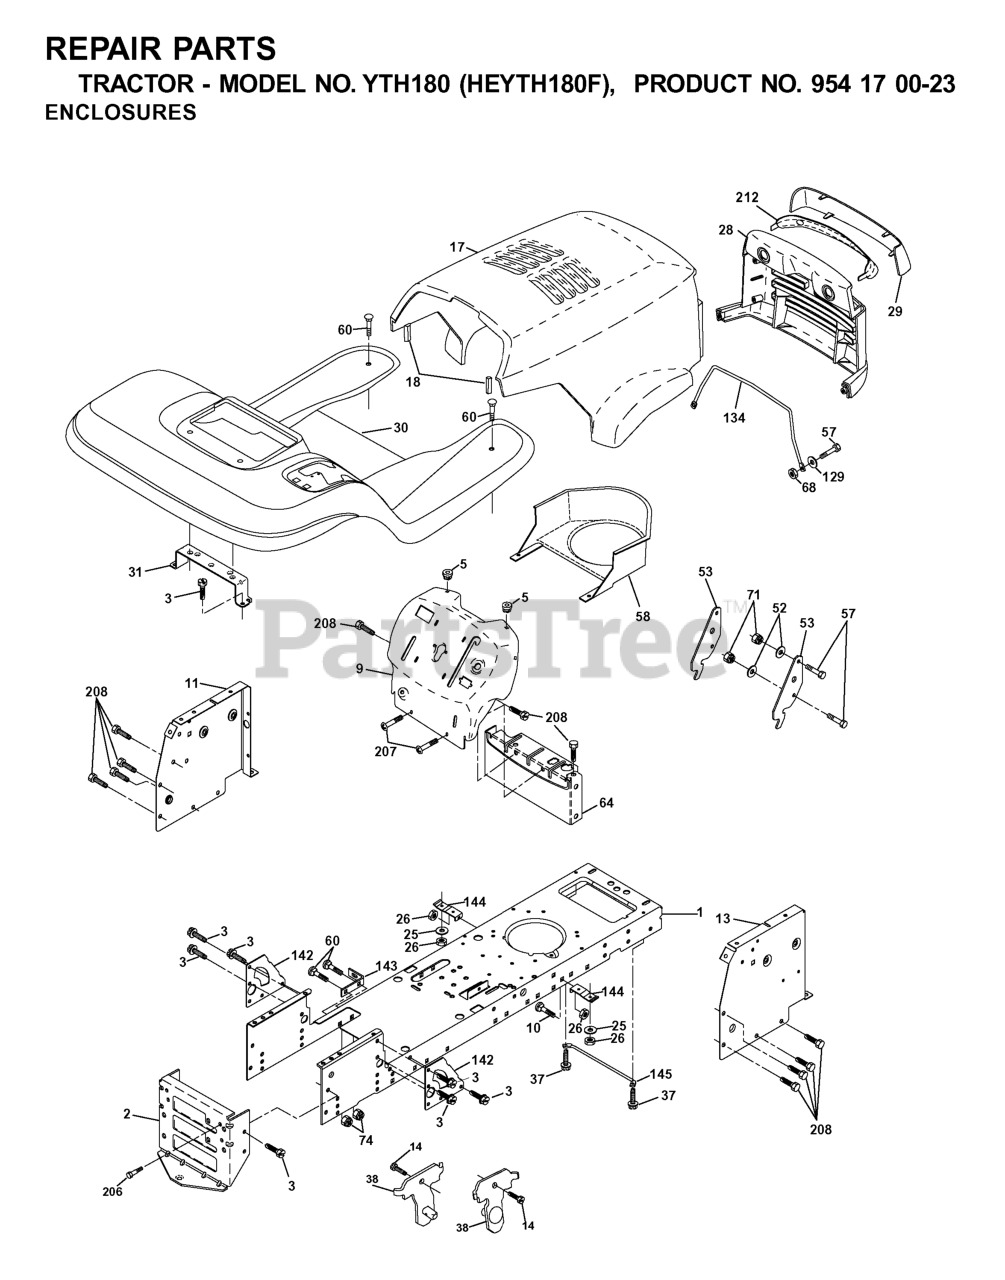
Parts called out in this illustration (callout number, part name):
1	CHASSIS STAMPING
2	DRAWBAR, 12GA
3	SCREW 3/8-16X3/4
5	BUMPER.RUBBER.HOOD
9	DASH(SUBS)
10	BOLT D
11	PANEL DASH LH
13	PANEL ASM, DASH RH
17	HOOD
18	BUMPER HOOD T
20	PLATE MTG
23	BUSHING.SNAP.NYL.BLK.
25	WASHER
26	NUT
28	GRILL
29	LENS
30	FENDER FOOTREST
31	BRACKET.SUPPORT.FENDER
37	Screw 5/16-18 x 1/2 Hex, Self Tapping 5/16-18 x 1/2
38	BRACKET.ASM.PIVOT.MOWER.REAR
53	BRACKET PNT PICK OFF LT/PL
57	BOLT
58	DUCT, INTAKE AIR
60	Bolt - Rd. Hd. Sq. Neckiage 3/8 16 x 3/4
64	DASH LOWER
68	NUT
71	NUT.CROWNLOCK.1/4
134	ROD SUPPORT HOOD LT/PL HUS.
142	PLATE
143	BRACKET, SWAY BAR
144	BRACKET FOOTREST
145	ROD PIVOT CHASSIS/HOOD
206	SHOULDER BOLT 5/16-18TT
207	SCREW, 5/16-18 X 1/2
208	SCREW 3/8-16X1/2
212	INSERT LENS REFLECTOR
